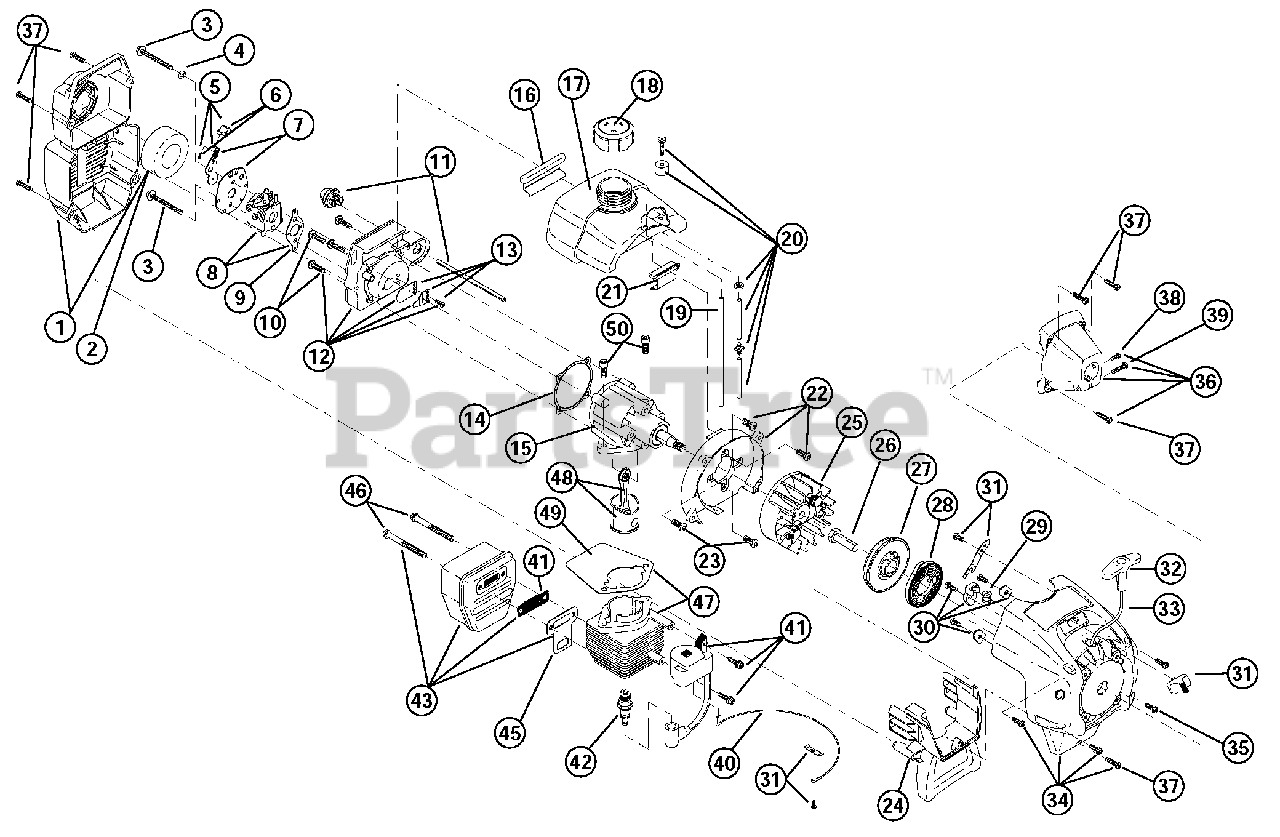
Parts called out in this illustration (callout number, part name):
1	Air Cleaner/Muffler Cover Assembly
2	Air Cleaner Filter
3	Carburetor Mounting Screw Assembly
4	Wavey Washer
5	Choke Lever Assembly
6	Choke Knob and Screw
7	Choke Lever and Plate
8	Carburetor Assembly
9	Carburetor Gasket
10	Carb Mount Screw
11	Primer and Hose Assembly
12	Carb Mount Assembly
13	Reed Assembly
14	Carburetor Mount Gasket
15	Crank Case Service Assembly
16	Rear Mounting Pad
17	Fuel Tank Assembly
18	Fuel Cap Assembly
19	Fuel Return Line
20	Fuel Line Assembly
21	Front Mounting Pad
22	Shroud Assembly
23	Shroud Screw
24	Shroud Extension and Stand
25	Flywheel Assembly
27	Recoil Pulley Assembly
28	Recoil Spring
29	Rope Guide
30	Pulley Retainer Assembly
31	Switch Assembly
32	Pull Handle
34	Starter Housing Assembly
35	Housing Screw
36	Clutch Cover Assembly
37	Cover Screws
38	Anti-Rotation Screw
39	Clamping Screw
40	Wire Lead
41	Module Assembly
42	Spark Plug
43	Muffler Assembly
44	Spark Arrestor Screen
45	Exhaust Gasket
46	Muffler Mounting Bolt Assembly
47	Cylinder Assembly
48	Piston and Rod Assembly
49	Cylinder Gasket
50	Cylinder Bolt
